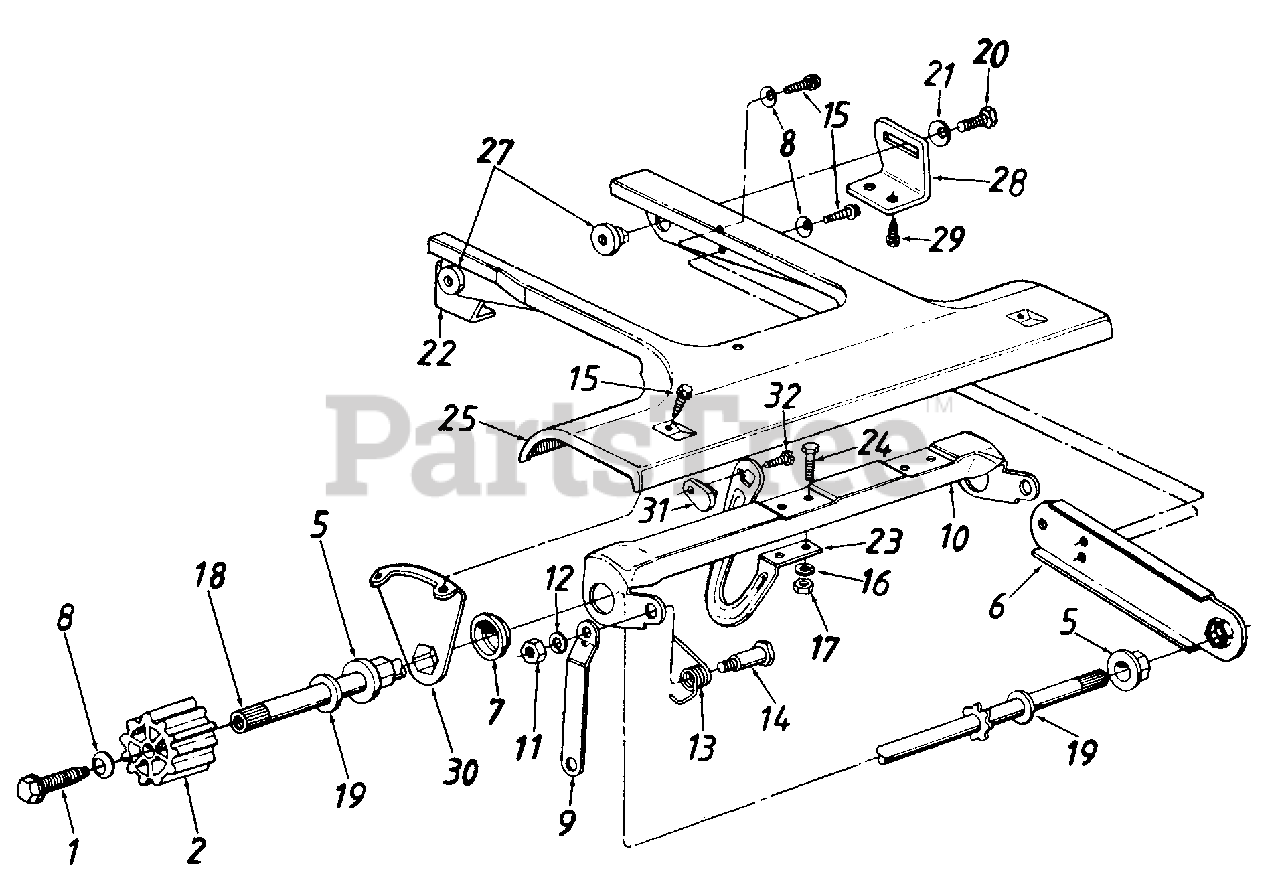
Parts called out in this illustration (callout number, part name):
1	Hex Wash. Hd. Tap Scr. 1/4-20 x .75" Lg.
2	Wheel Drive Pinion
5	Hex Flange Brg. .504" I.D.
8	Bell-Wash. .265" I.D. x .75" O.D.
9	Link 5.06" Lg.
10	Drive Engagement Cam
11	Hex Nut 5/16-18 Thd.
12	L-Wash. 5/16" I.D.
13	Torsion Spring-R.H.
14	Shoulder Bolt .437" Dia.
15	Hex L-Wash. Hd. AB-Tap Scr. 1/4" x.62" Lg.
16	L-Wash. 1/4" I.D.
17	Hex Nut 1/4-20 Thd.
18	Drive Shaft Ass'y.
19	Fl-Wash. .531" I.D. x .93" O.D.
20	Hex Bolt 5/16-18 x .62" Lg.
21	Bell-Wash. .345" I.D. x .88" O.D.
22	Pivot Bracket-R.H.
25	Front Pinion Pivot Cover
27	Shoulder Nut
28	Pivot Bracket-L.H.
29	Hex Wash. Hd. AB-Tap Scr. 1/4 x .62" Lg.
32	Hex B-Tap Scr. #10 x .44" Lg.
